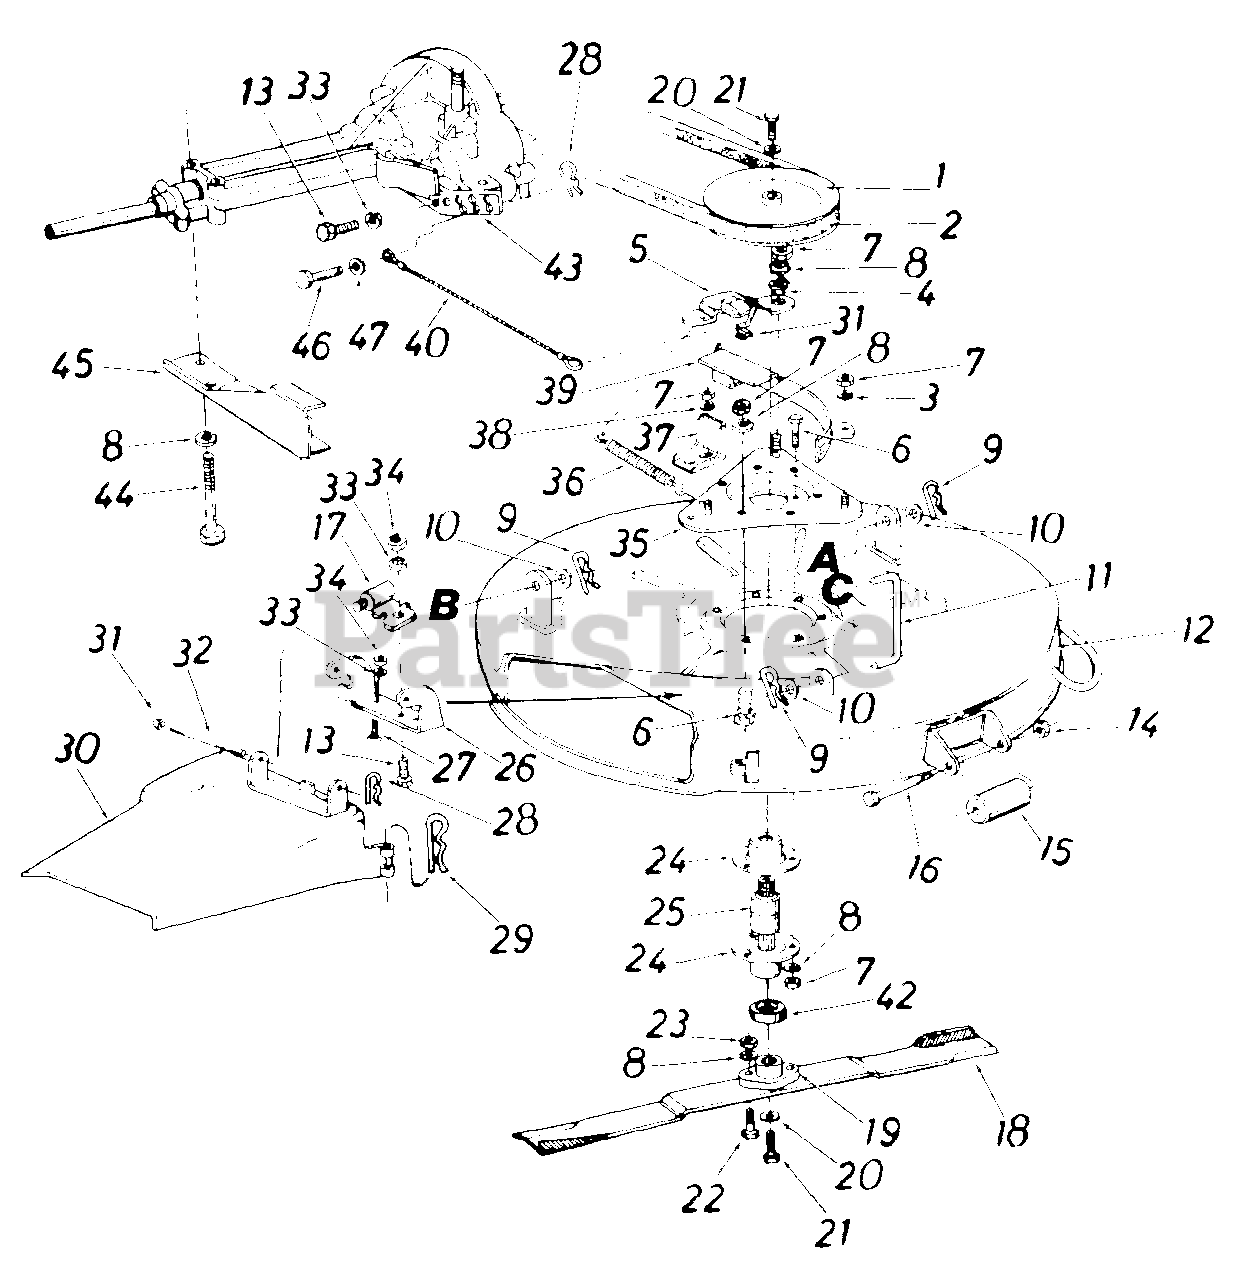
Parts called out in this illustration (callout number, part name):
1	Deck Pulley 7.00" O.D.
2	"V"-Belt 1/2" x 52" Lg.
3	Belleville Washer
4	Shoulder Spacer
5	Blade Brake Brkt. Ass'y.
6	Hex Bolt 5/16-18 x .75" Lg.*
7	Hex Nut 5/16-18 Thd.*
8	L-Wash. 5/16" I.D.*
9	Intern. Cotter Pin 1/2" Dia.
10	Fl-Wash. .531" I.D. x .930"
11	Deck Link 3.9" Lg.
12	30" Deck Ass'y.
13	Hex Bolt 1/4-20 x .62" Lg.*
14	Hex Nut 3/8-16 Thd.*
15	Skid Roller
16	Shoulder Bolt .498" Dia. x 4.75
17	Safety Switch
18	30" Blade
19	Blade Adapter
20	L-Wash. 3/8" I.D.-H.D.
21	Hex Bolt 3/8-24 x .75" Lg.*
22	Hex Bolt 5/16-24 x 1.00"*
23	Hex Nut 5/16-24 Thd.*
24	Housing Bearing Spindle
25	Blade Spindle
26	Deck Hinge Brkt.
27	Carriage Bolt 1/4-20 x .62"
28	Intern. Cotter Pin 5/16" Dia.
29	Cotter Pin
30	Chute Deflector Ass'y.
31	Cap Speed Nut 1/4" Rod
32	Hinge Pin
33	L-Wash. 1/4" I.D.
34	Hex Nut 1/4-20 Thd.*
35	Spindle Mtg. Bracket Ass'y.
36	Extension Spring .38" O.D. x 3.25" Lg.
37	Belt Keeper Ass'y.
38	Belleville Wash. 5/16" I.D.
39	Belt Guard
40	Brake Cable Ass'y.
42	Bearing Guard
43	Lower Inside Belt Guard
44	Hex Bolt 5/16-18 x 2.75"
45	Lower Outside Belt Guard
46	Clevis Pin 1/4" x 1/2"
47	Fl-Wash. 1/4" I.D. x .50" O.D.
